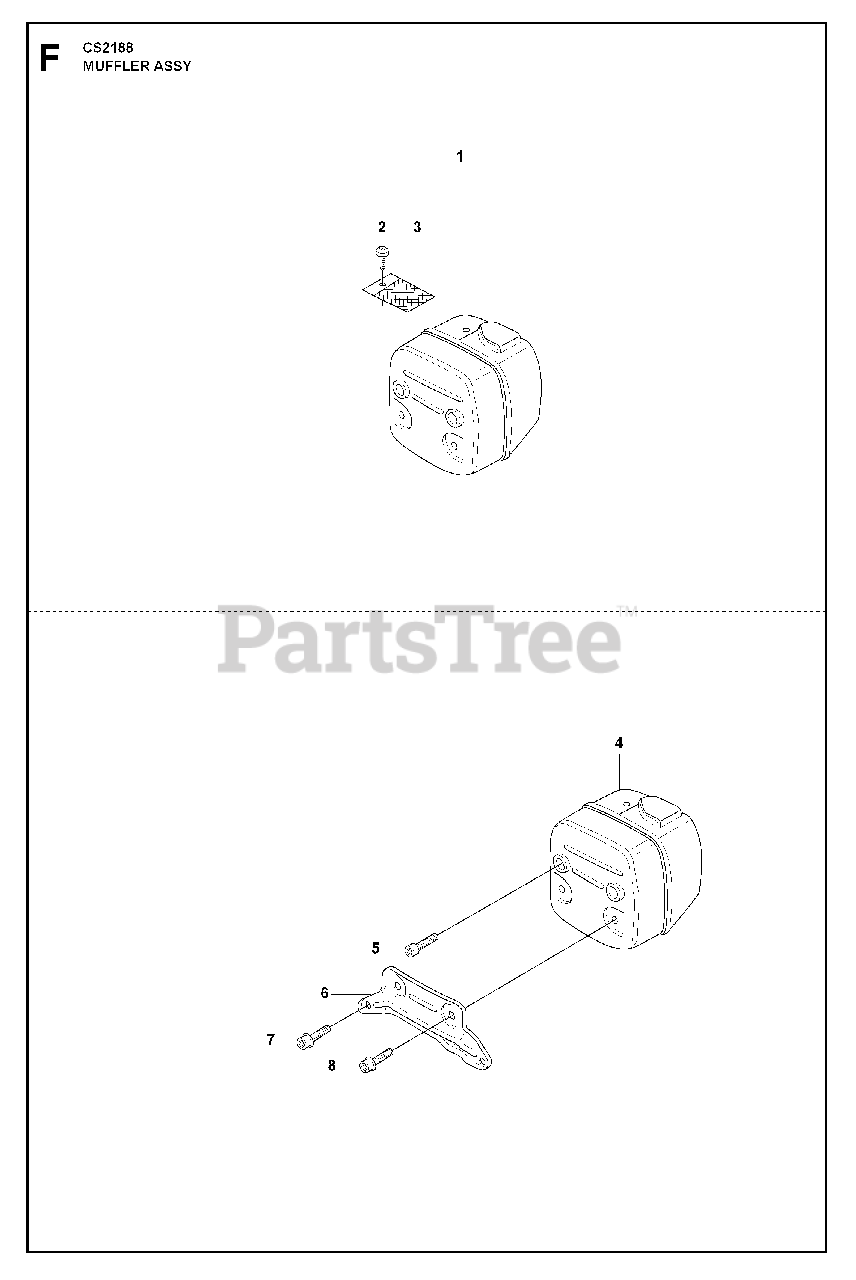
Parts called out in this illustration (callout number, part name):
1	MUFFLER ASSY
2	SCREW
3	SCREEN
4	MUFFLER ASSY
5	SCREW MC6S 6X20
6	SUPPORT
